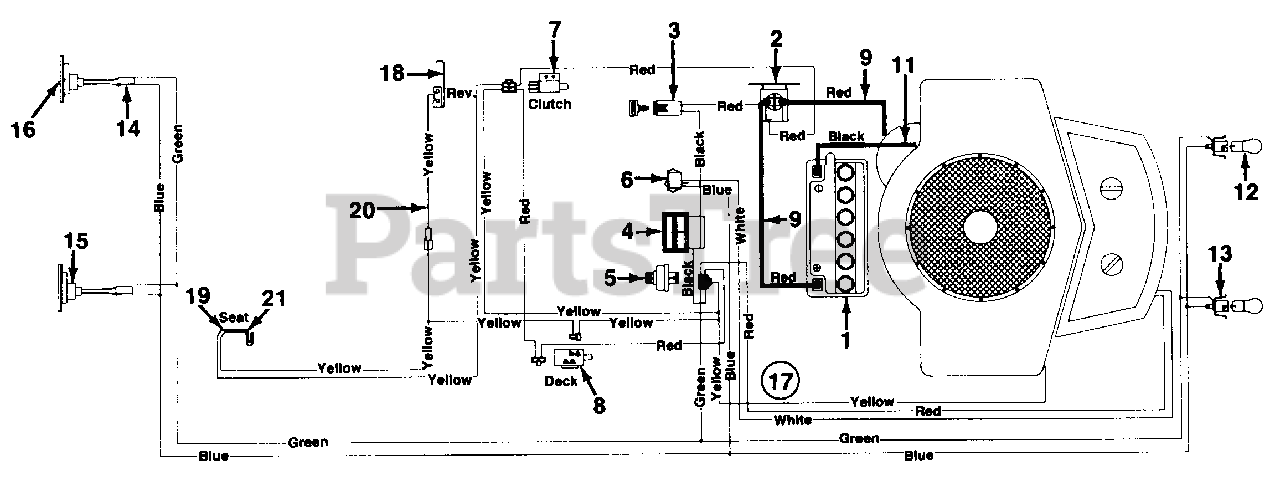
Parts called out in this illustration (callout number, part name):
1	Battery (275 Cold Crank Amps)
2	Solenoid
3	Fuse 7.5 Amps
4	Ammeter
5	Ignition Switch
6	Light Switch
7	Safety Switch
8	Safety Switch
9	Electric Wire l4n Lg.
11	Ground Wire 7.5" Lg.
12	Lamp
13	Socket
14	Taillight Harness
15	Taillight Ass'y.
16	Taillight Bulb
17	Wire Harness
18	Spring Switch
19	Spring Switch
20	Transmission Ext. Wire
21	Seat Safety Switch
